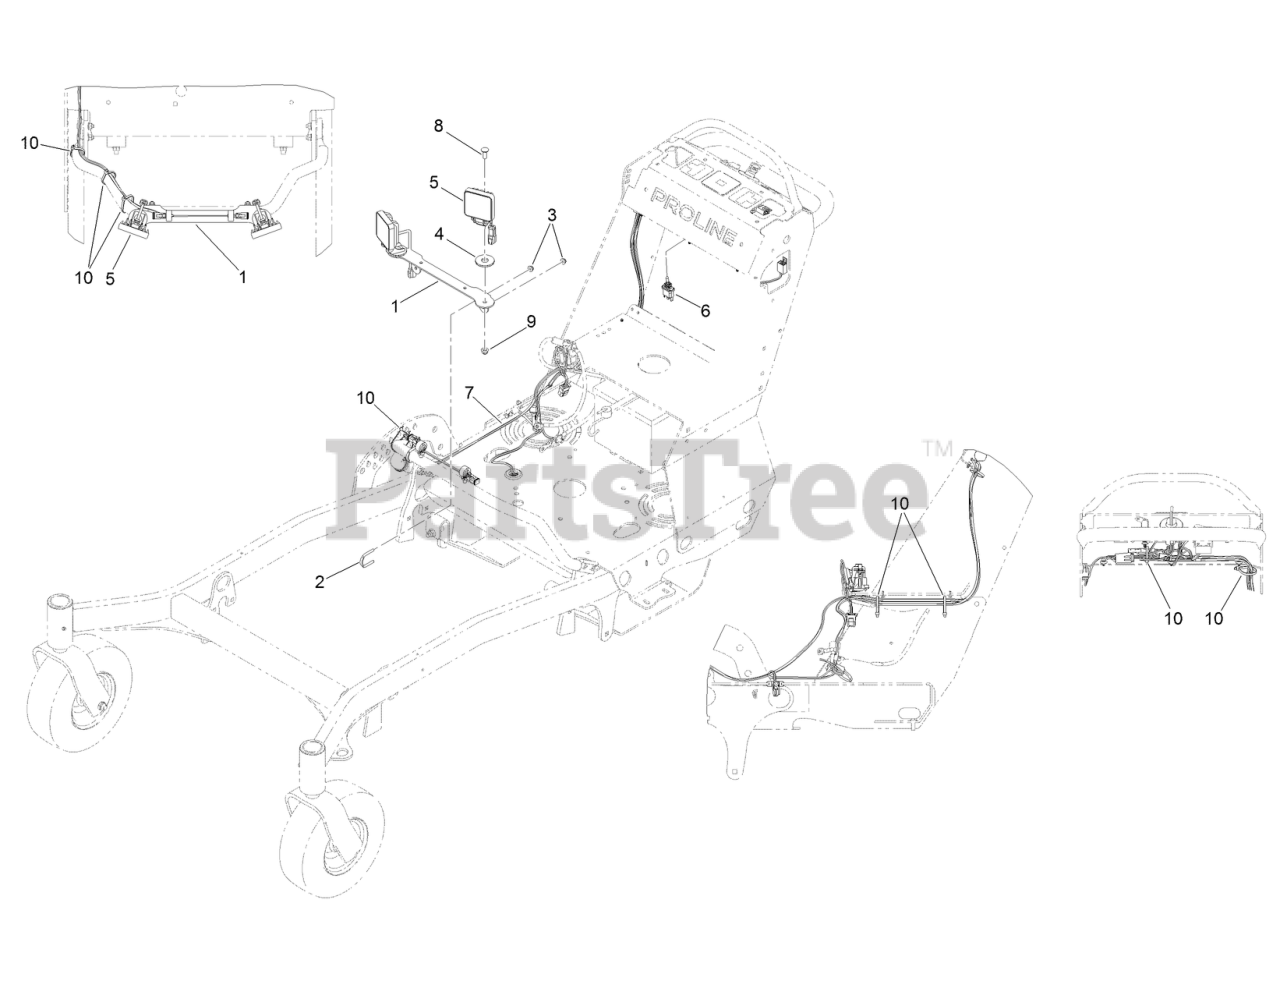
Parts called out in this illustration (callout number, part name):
2	CLAMP-LIGHT
3	NUT-HF
4	WASHER-FRICTION, COMPOSITE
5	LIGHT-WORK, LED
6	SWITCH-TOGGLE, SPDT ON-ON 12A
7	HARNESS-WIRE, LIGHT KIT
8	BOLT-CARR
9	NUT-HF, NI
10	TIE-CABLE
